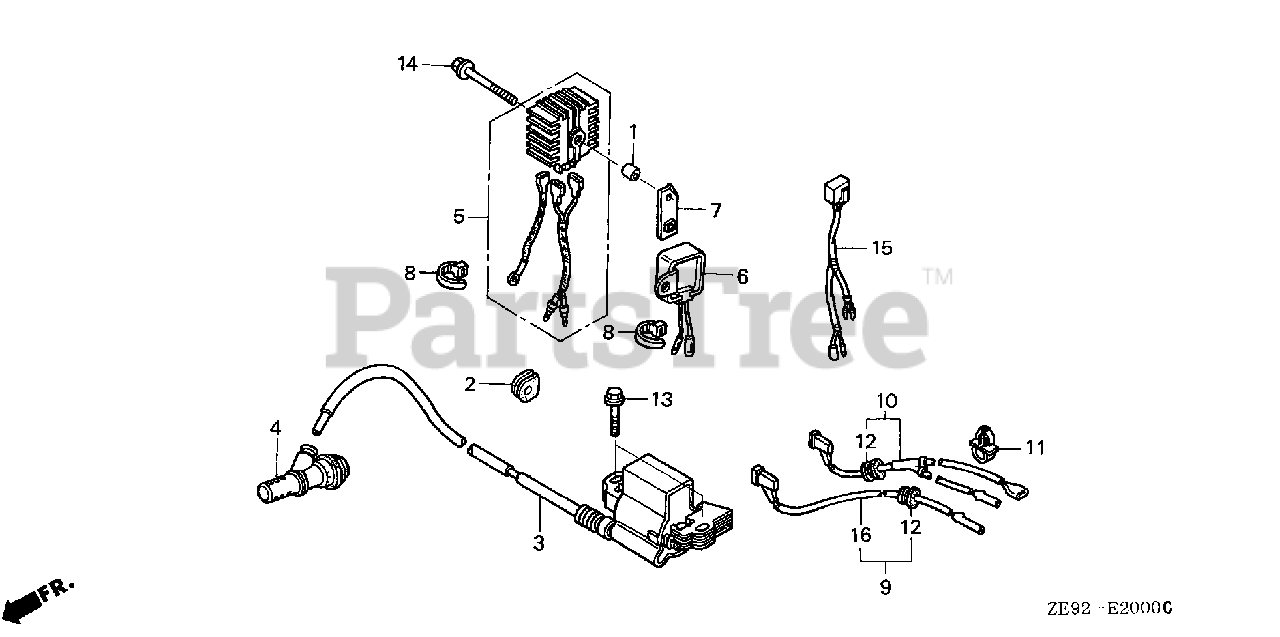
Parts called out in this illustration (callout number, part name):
3	COIL ASSY., IGNITION
4	CAP ASSY., NOISE SUPPRESSOR
6	RECTIFIER, SILICON
8	BAND B1, WIRE
9	WIRE, STOP SWITCH
12	GROMMET, WIRE CORD
13	BOLT, FLANGE (6X28) (CT200)
